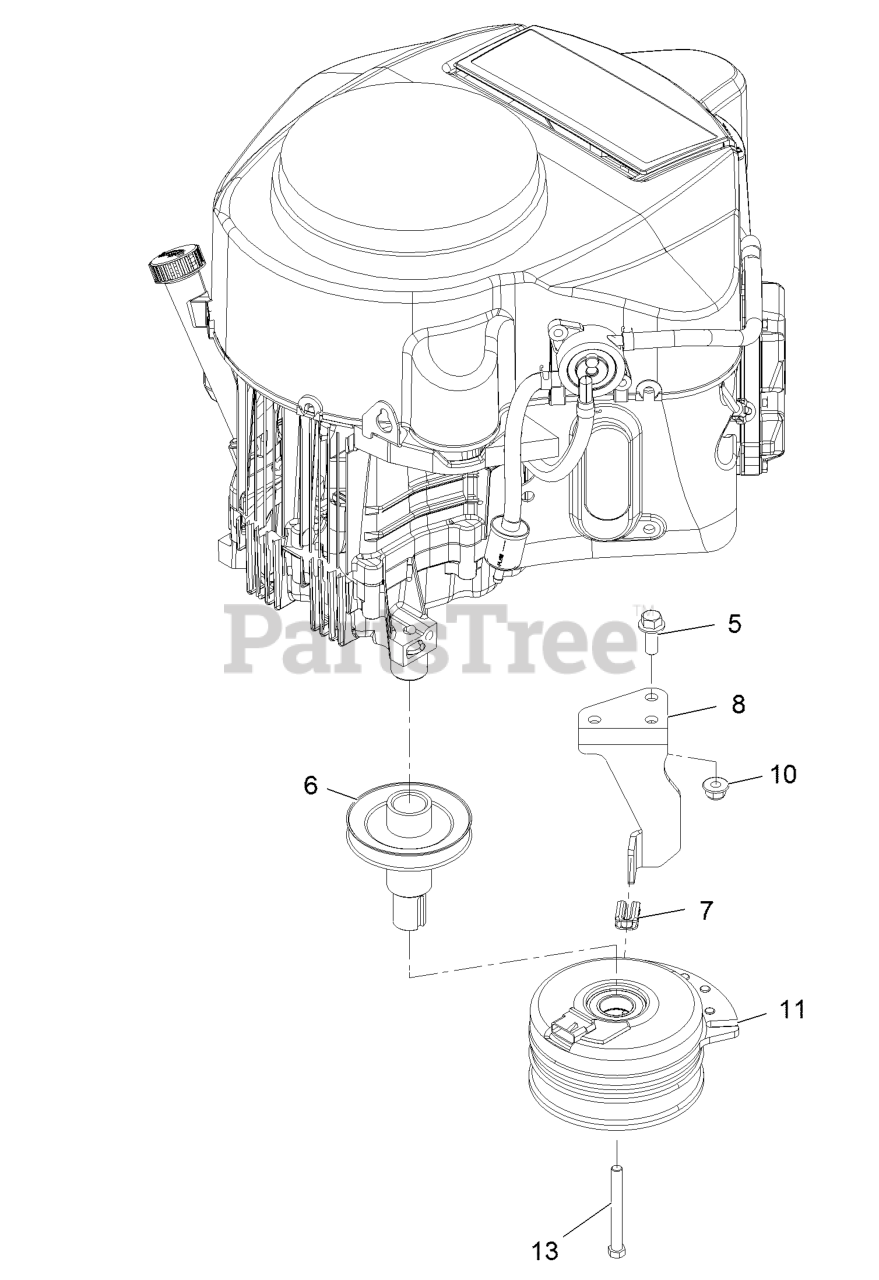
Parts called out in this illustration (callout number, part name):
5	SCREW-HHF 3/8-16 X 1
6	PULLEY-ENGINE
7	ISOLATOR-CLUTCH
8	STOP-CLUTCH (NARROW)
10	NUT-HF, NI
11	CLUTCH-ELECTRIC
13	PIN-ROLL, SLOTTED
